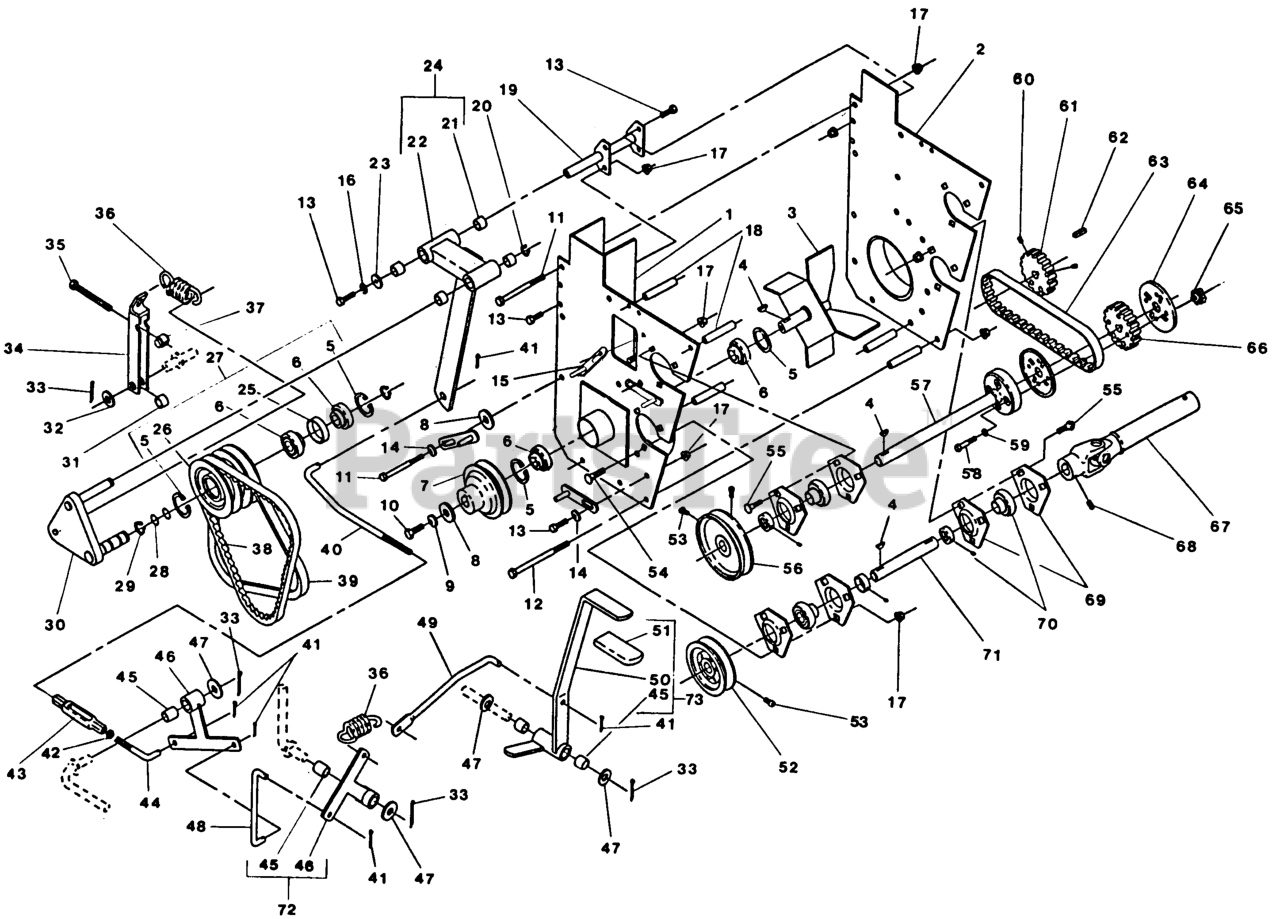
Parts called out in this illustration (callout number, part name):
2	WLD,PANEL FRONT
4	KEY-WOODRUFF
6	BEARING
12	SCREW-HH
14	WASHER-SPRING
16	WASHER-LOCK
22	Control Wldm't - Tmfr. Sheave
24	CNTRL ASSY,TRANS SHV
25	SPACER,TRANSFER BEARING
28	O-RING,
36	SPRING,BELT TENSION
37	SWIVEL,BELT TENSION
38	BELT,B SIZE 43.5
39	BELT,SECONDARY DRIVE
40	ROD,PTO LOW RH THD
44	ROD,PTO RH LOW LH THD
45	SLEEVE-BEARING
49	ROD,PTO UPPER
51	GRIP-LEVER
52	SHEAVE,5.5 B
53	SCREW-SET
56	SHEAVE,7 B
58	SHEAVE,7 B
59	WASHER-LOCK
63	BELT,DRIVE POSITIVE
69	HOUSING-FLANGE
70	BEARING,W/COLLAR
71	JACKSHAFT,PTO
